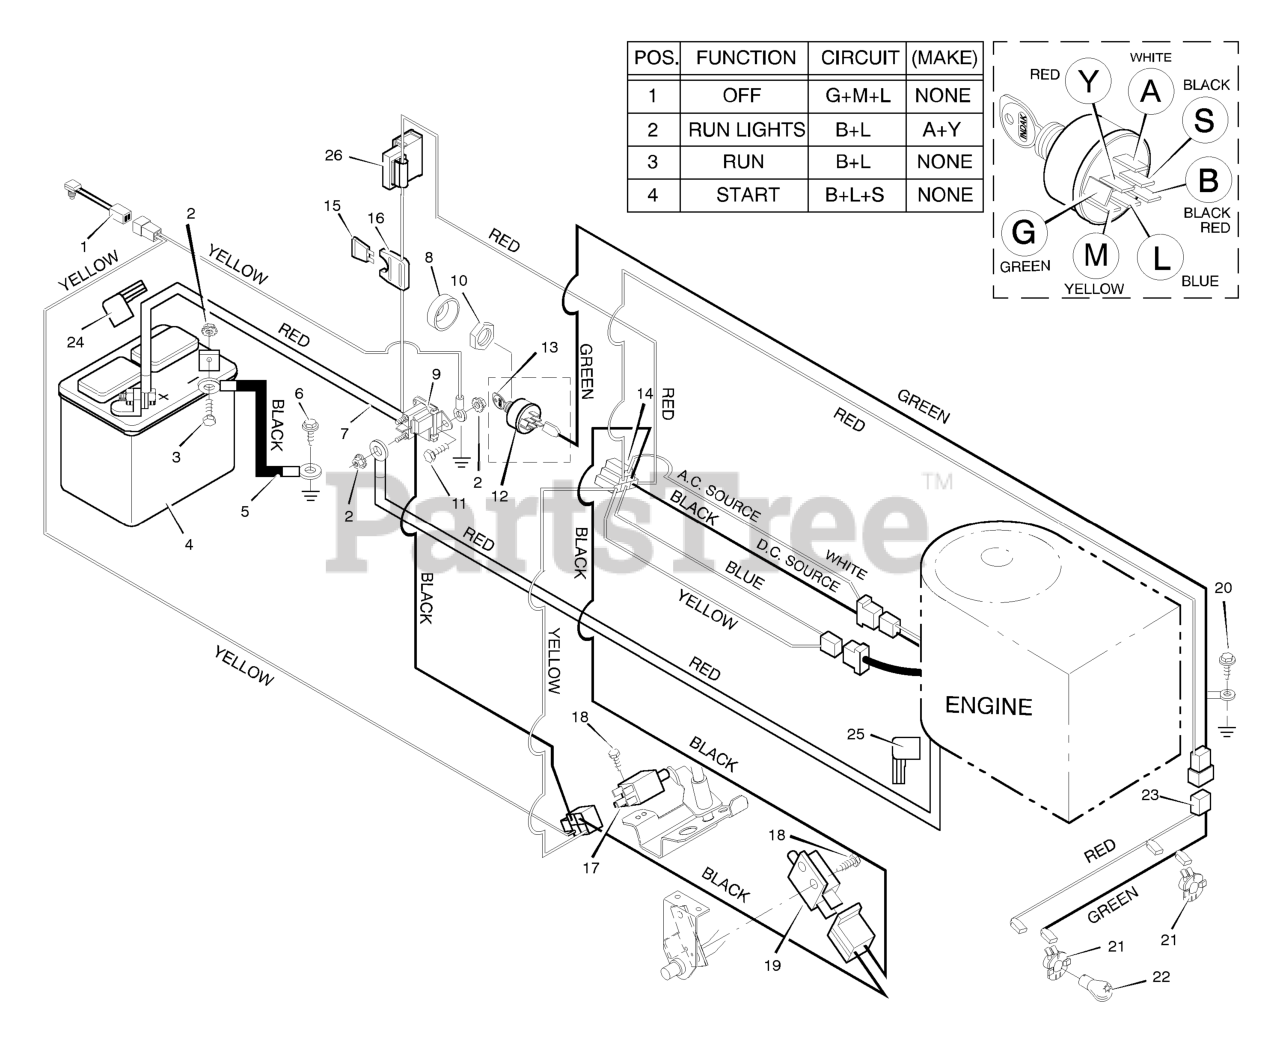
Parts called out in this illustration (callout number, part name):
1	Switch, Seat Sensor
2	Locknut
3	Bolt, Hex
4	Battery
5	Cable, Battery Ground
7	Cable, Red Battery
8	Cap, Ignition
9	Solenoid
10	Nut
12	Switch, Ignition
13	Key, Ignition
14	Harness, Chassis Wire
16	Holder, Fuse
17	Switch, Clutch
19	Switch, Clutch
20	Screw
21	Socket, Light
22	Bulb, Light
23	Harness, Light Wire
24	Cover, Terminal
25	Cover,
26	Ammeter
